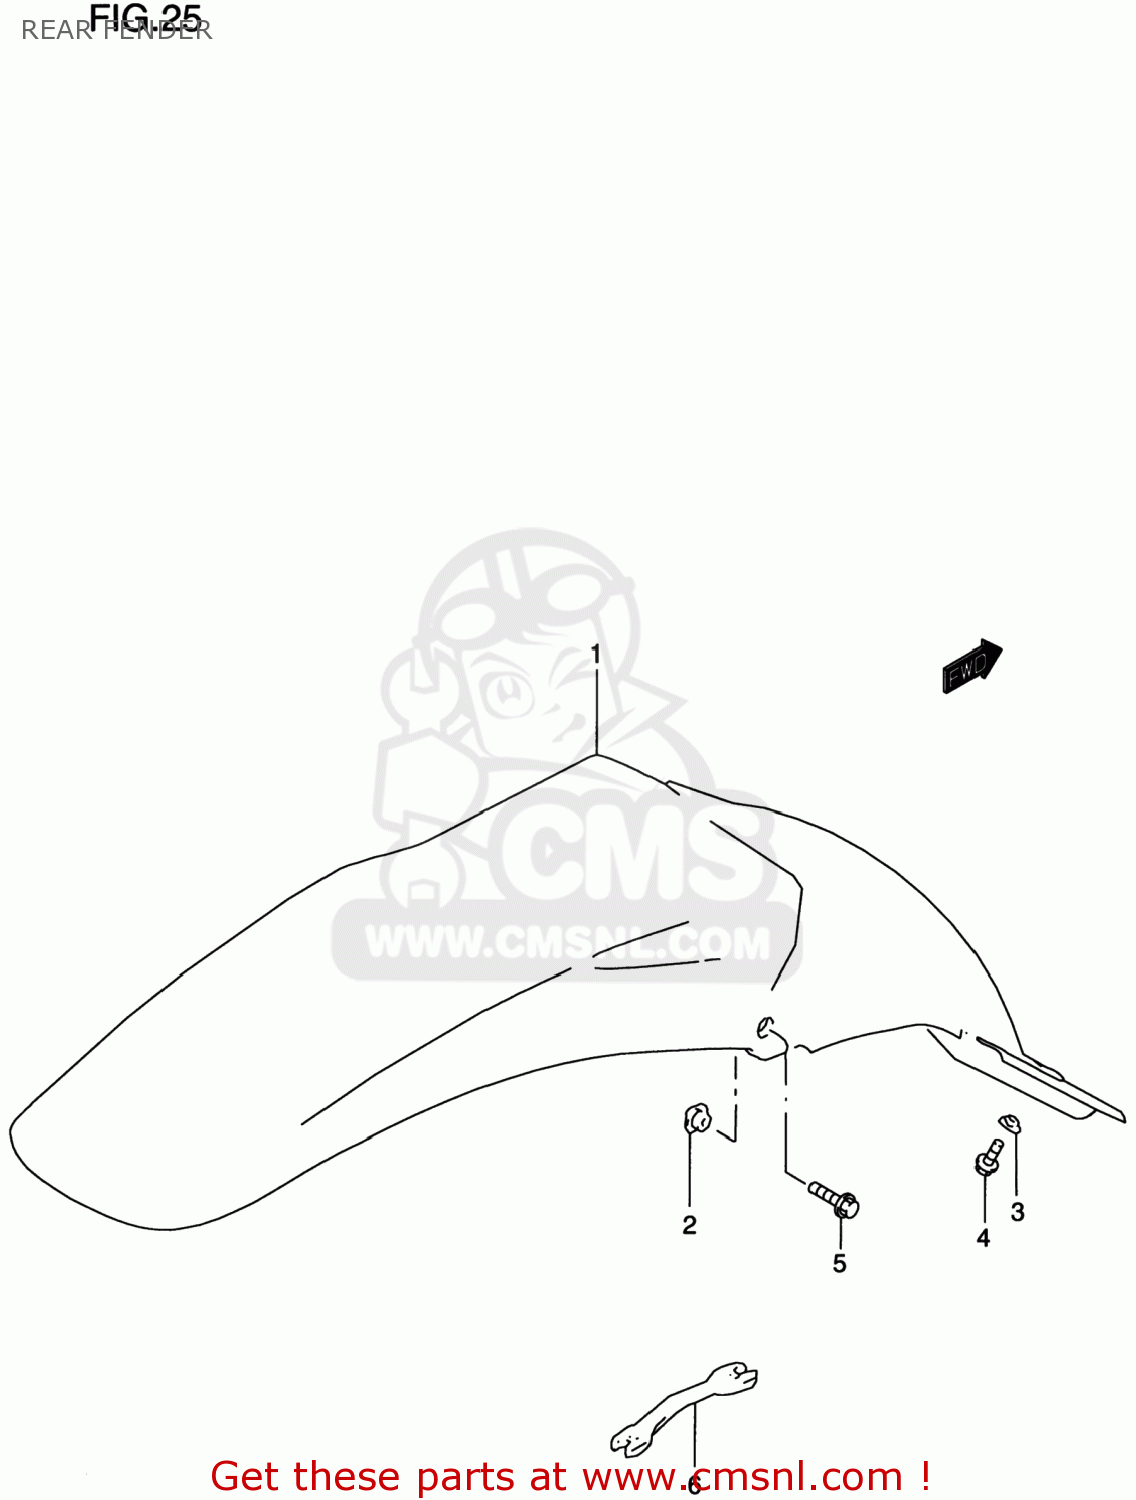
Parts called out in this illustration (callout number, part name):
1	FENDER,RR
2	NUT
3	WASHER
4	BOLT
5	SCREW
6	SPANNER,OPEN
